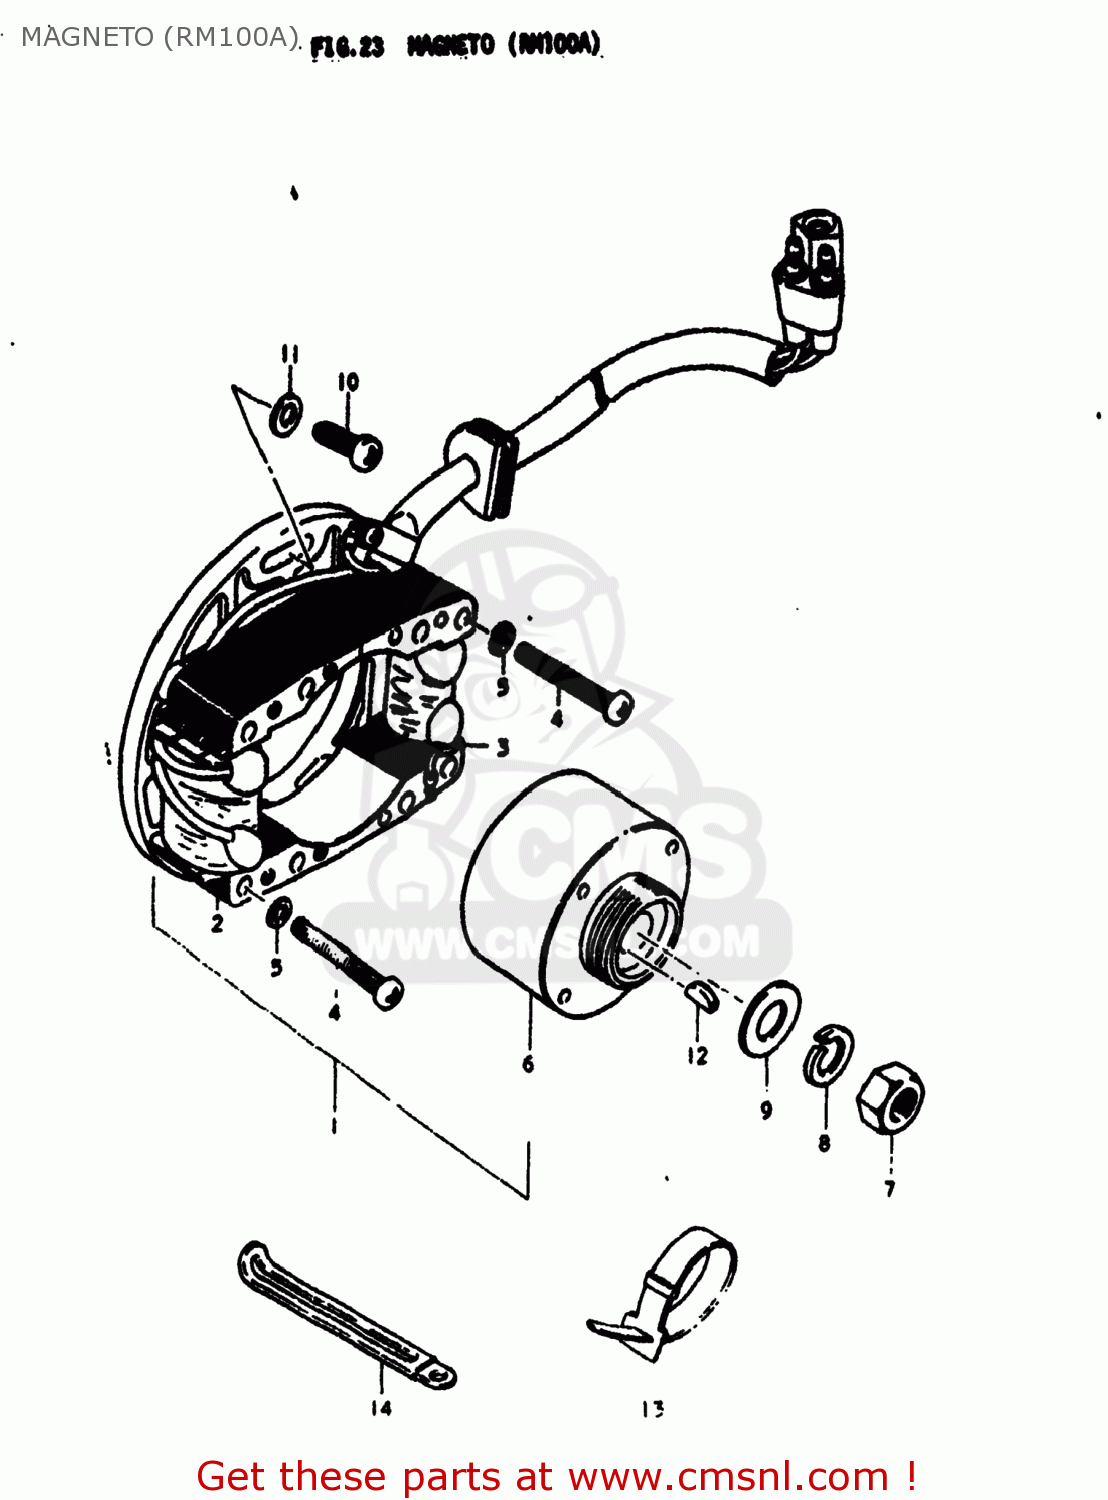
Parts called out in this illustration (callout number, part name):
1	MAGNETO ASSEMBLY
2	COIL
3	COIL,PULSER
4	SCREW
5	LOCK WASHER
6	ROTOR ASSEMBLY
7	NUT (10MM)
8	LOCK WASHER
9	WASHER
10	SCREW
11	WASHER
12	KEY
13	CLAMP
14	CLAMP
